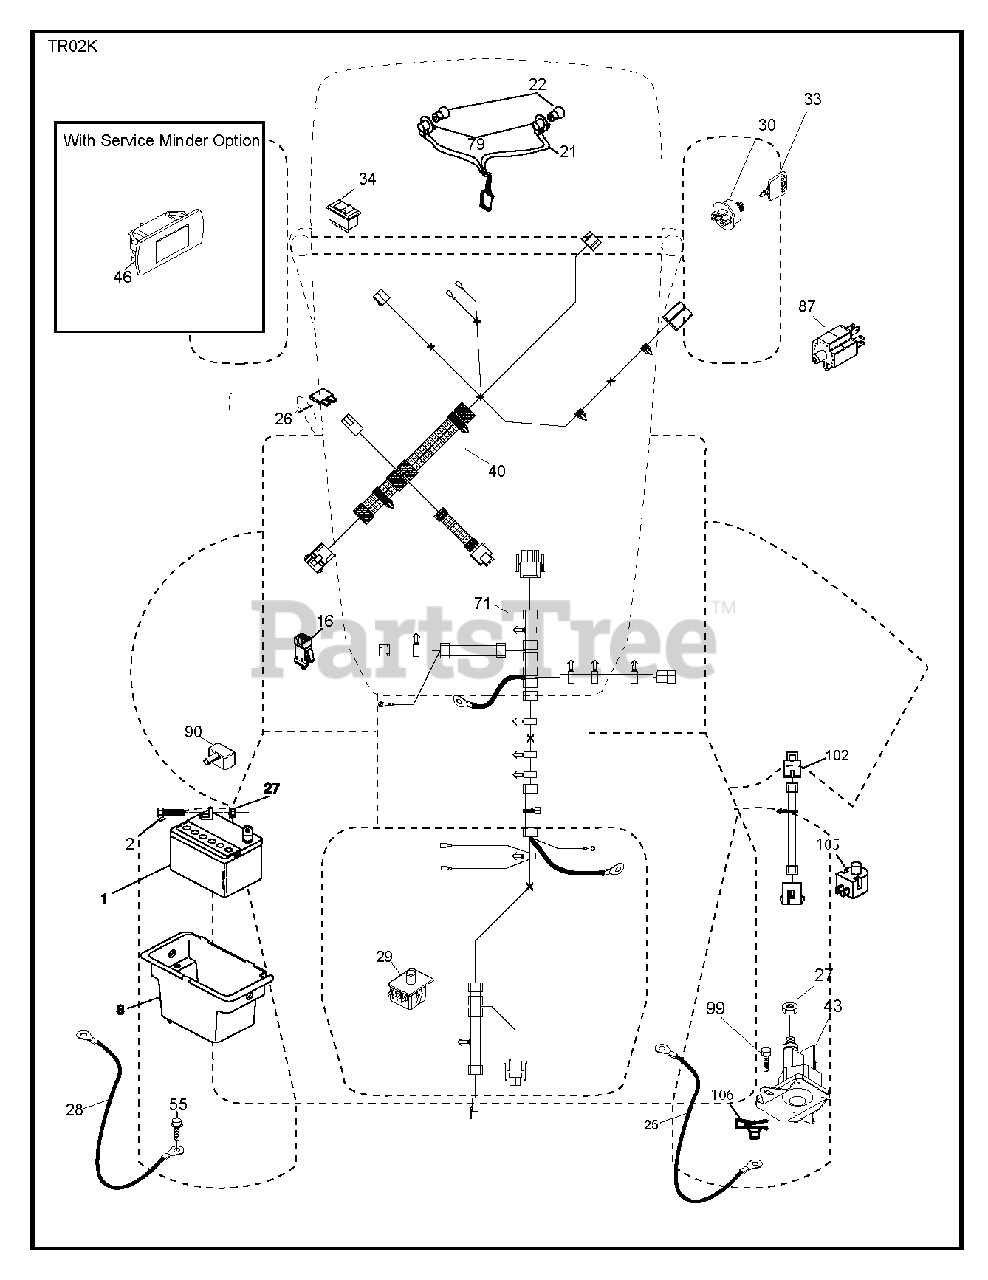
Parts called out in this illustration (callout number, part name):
1	REPL BY 532 12 38-99
2	BOLT.HEX.1/4.X.3/4.DICHROMATE
8	BOX.BATTERY.MNT.REAR.L
16	SWITCH INTERLOOK PUSH-IN
21	HARNESS.LIGHT W/4152J BULBS
22	LIGHTBULB
25	CABLE.BATT.RED.8GA.17
26	FUSE 20AMP
27	NUT
28	CABLE.GROUND.REAR.BATTERY.8G
29	SWITCH.SEAT.DP W/RAMPS
30	SWITCH.IGN.DELTA.W.LGH.ROS
33	KEY.CHAIN.BLISTER.PACK.GEN.USA
34	SWITCH LT
40	HARNESS.TEX.DASH.MAN.REAR BATT
43	SOLENOID.W/BRASS.PLUNGER
55	SCREW 5/16"
71	HARNESS.TEX.CHSSIS.REAR.BATT
79	BULB HOLDER ASM.
87	SWITCH.INTRLCK.CLUTCH.
90	COVER.TERMINAL.BATTERY
99	SCREW HEXWSHR 1/4-20X3/4
102	HARNESS.PIGTAIL.VAR.SD.FC
105	REVERSE SWITCH
106	1/4-20 U NUT
